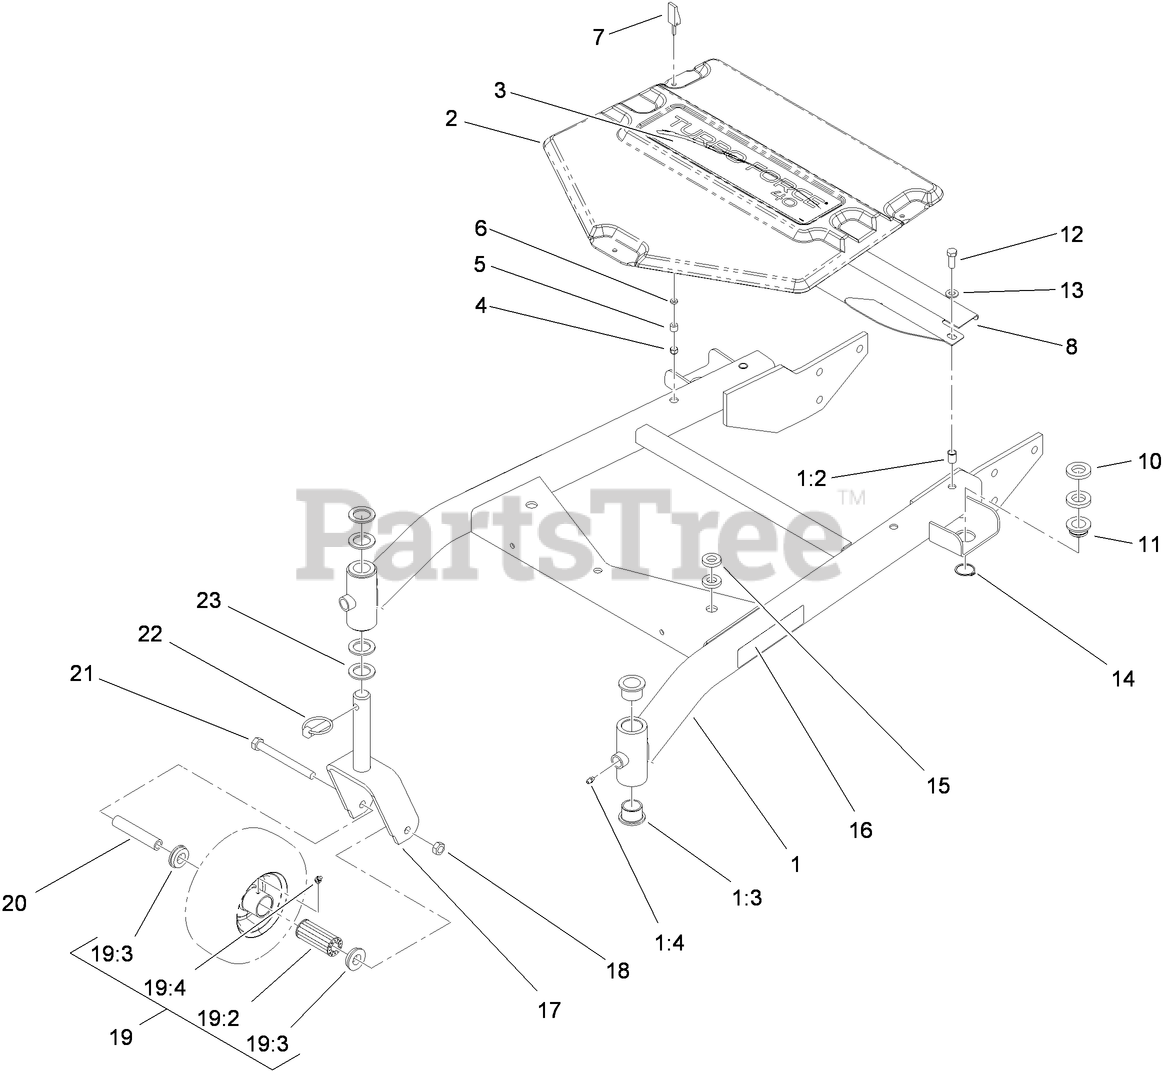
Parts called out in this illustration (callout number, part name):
1	CARRIER FRAME ASM
1:2	INSERT-NUT
1:3	BUSHING
1:4	FITTING-GREASE
2	COVER-FRAME, CARRIER
4	NUT-LOCK, HH
5	BUSHING-LATCH, SWELL
6	WASHER
7	HANDLE-LATCH, SWELL
8	SHIELD-BELT
10	SPACER-SUPPORT, DECK
11	BUSHING-DECK
12	SCREW-HH
13	WASHER-FLAT
14	RING-RETAINING
15	SPACER
16	DECAL-HOC
17	FORK-CASTOR
18	NUT-HEX
19	WHEEL AND TIRE ASM
19:2	BEARING-ROLLER
19:3	BUSHING
19:4	FITTING-GREASE
20	BUSHING-SPANNER
21	SCREW-HH
22	PIN-LYNCH
23	WASHER-THRUST
